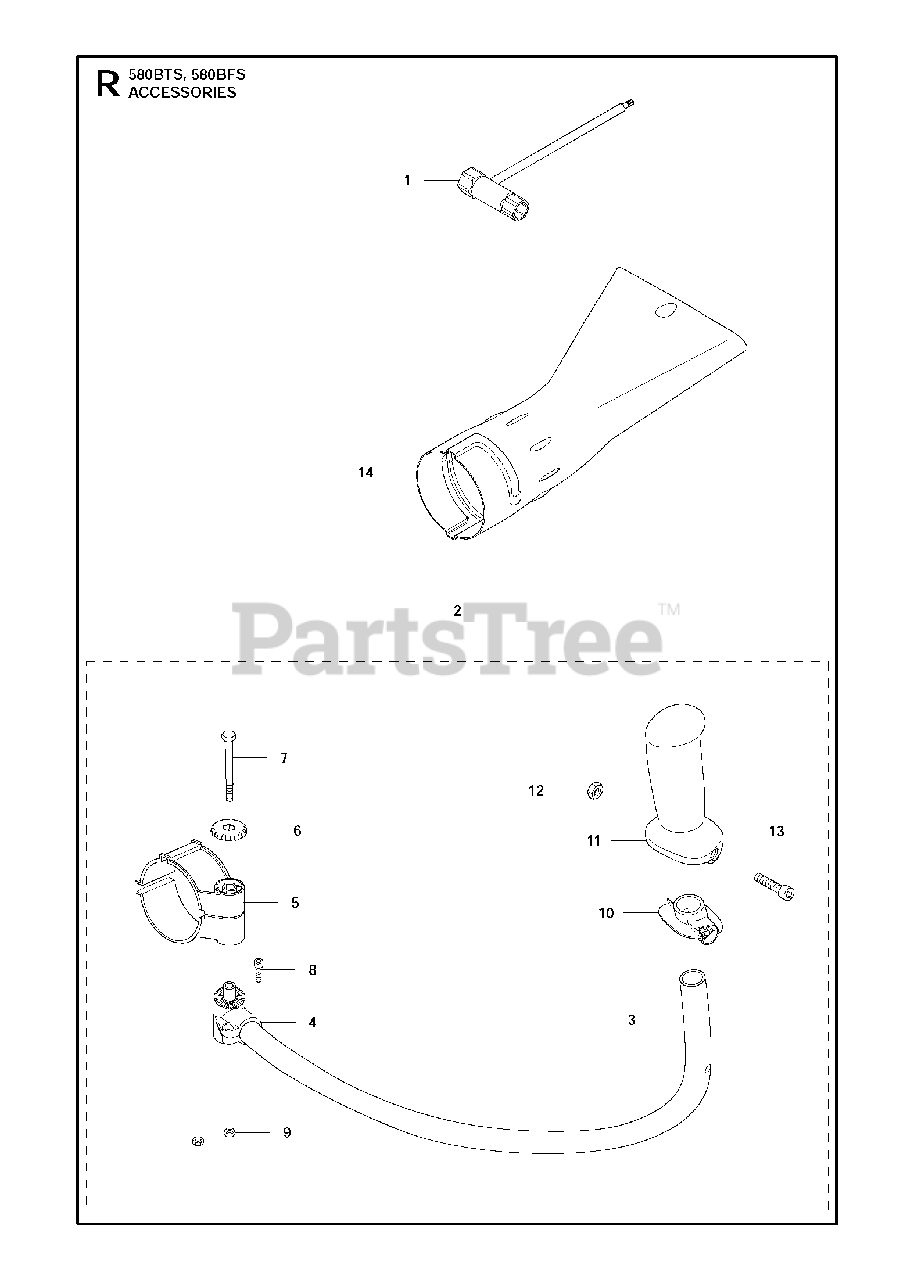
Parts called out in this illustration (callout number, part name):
2	HANDLEBAR ASSY
3	HANDLE
4	HOLDER
5	HANDLE HOLDER
6	KNOB
7	SCREW
8	SCREW MC6S 5X10
9	NUT
10	BRACKET
11	HANDLE
12	NUT
13	SCREW
14	NOZZLE FLAT
